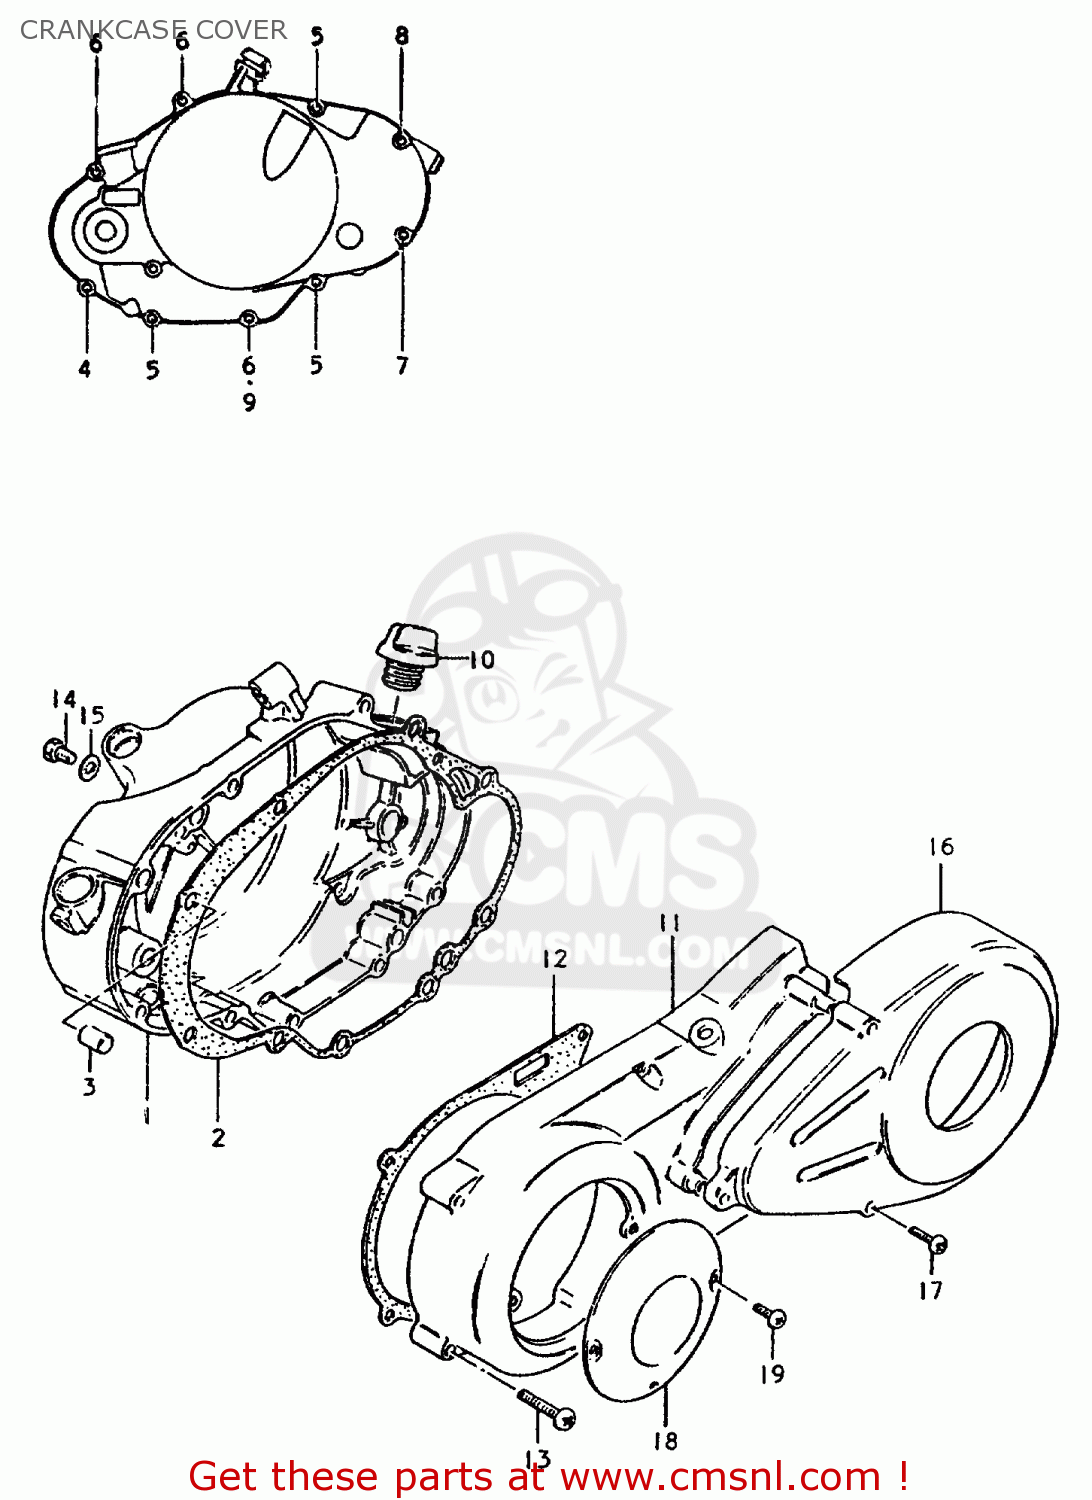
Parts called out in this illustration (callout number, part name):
1	COVER SET,CLUTCH
2	GASKET,CLUTCH COVER (MCA)
3	PIN
4	SCREW
5	SCREW 6X30
6	SCREW
7	SCREW
8	SCREW 6X60
9	GASKET(6.2X11X1).2 (NAS)
10	PLUG
11	COVER, MAGNETO
12	GASKET,MAGNETO COVER (NAS)
13	SCREW (6X35)
14	SCREW(6X10)
15	GASKET(6.2X11X1) (NAS)
16	GASKET, CYCLE CHAIN
17	SCREW
18	CAP,MAGNETO INSPECTION
19	SCREW
